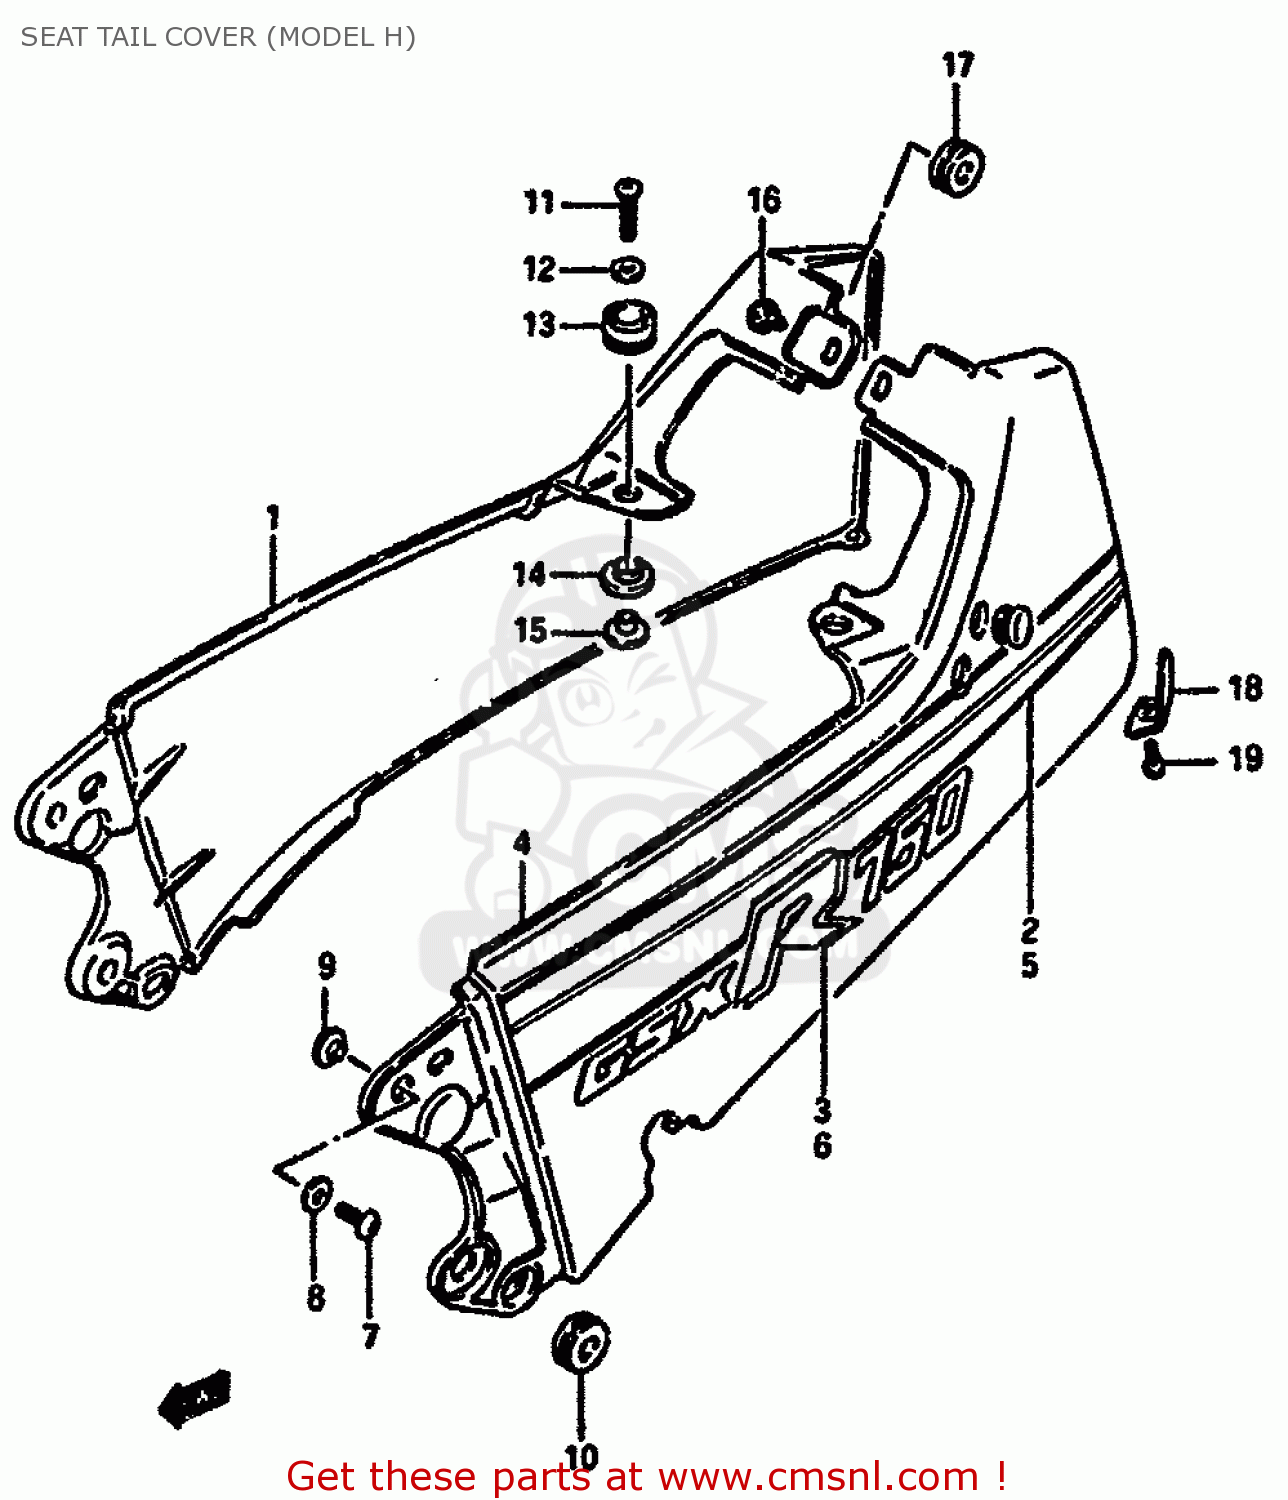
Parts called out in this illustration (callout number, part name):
1	COVER,SEAT TAIL RH
2	TAPE SET,SEAT TAIL COVER
3	EMBLEM
4	COVER,SEAT TAIL
5	TAPE SET,SEAT TAIL COVER
6	EMBLEM
7	SCREW
8	WASHER
9	WASHER
10	CUSHION
11	SCREW
12	WASHER
13	CUSHION,TAIL COVER UPR
14	CUSHION,TAIL COVER LWR
15	SPACER,SEAT TAIL COVER
16	CLIP
17	CUSHION
18	PLATE,SEAT TAIL COVER,L
19	SCREW
